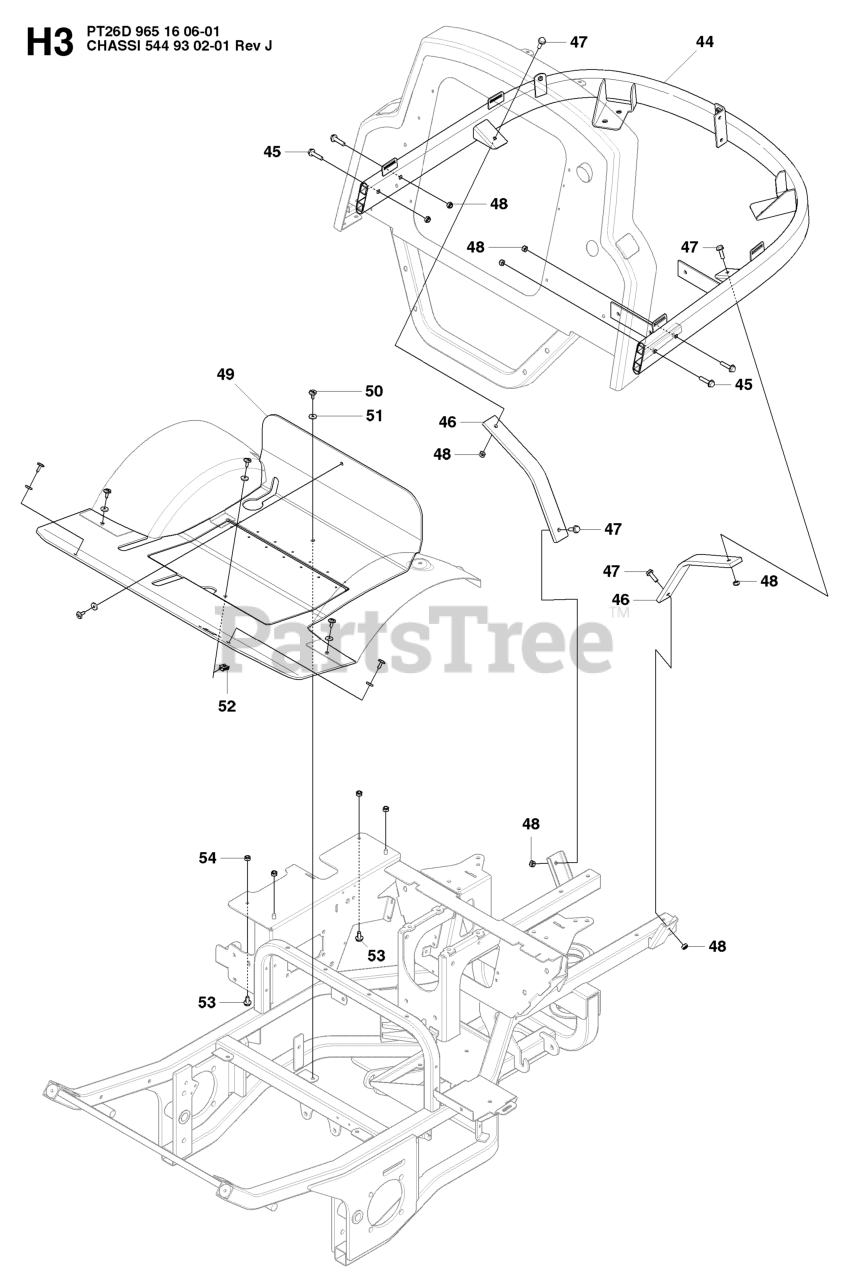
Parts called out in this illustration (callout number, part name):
45	SCREW EHHFM
47	BOLT
48	LOCKNUT M8
54	LOCKNUT M8
